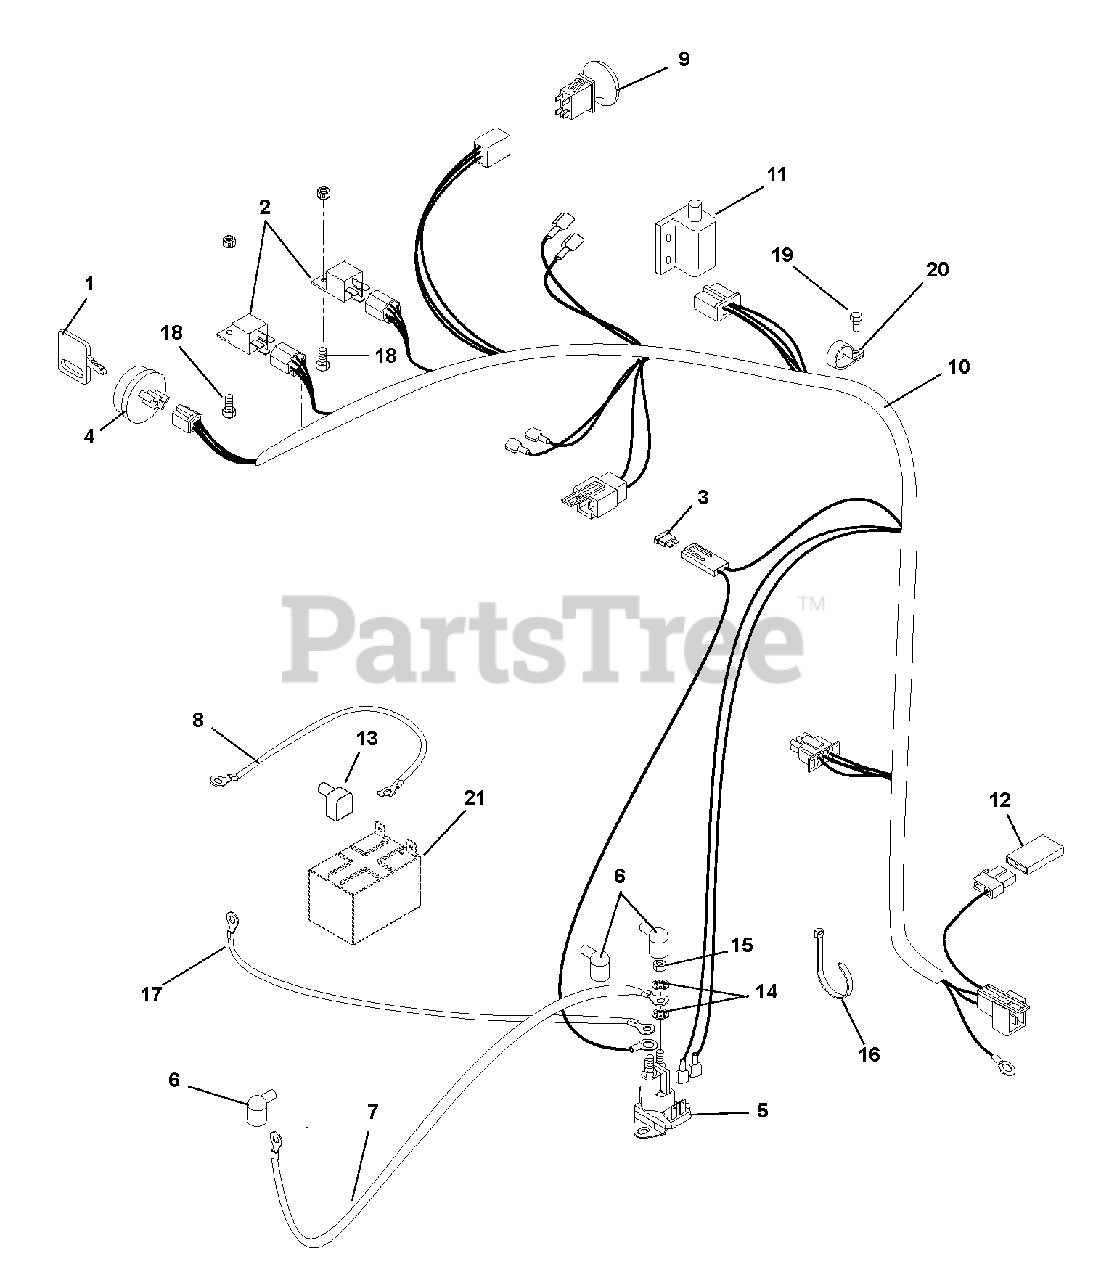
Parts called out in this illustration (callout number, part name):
1	Key with Cap
2	Relay
3	Fuse, 30 AMP
4	Key Switch
5	Solenoid
6	Boot, Eyelet Terminal
7	Starter Cable
8	Cable, Ground .25 x 13.00 x .31
9	Switch, Clutch With Retainer
11	Switch, Double Pole N.O. / N.O.
12	Diode, Connector Shell
13	Insulator
14	Washer, Locking .31
15	Nut, Jam .31-24
16	Cable Tie
17	Starter Cable
18	Screw, Hex Washer Head Machine 10-24 x .75
19	Screw, Tapping Hex Washer Head Thread Rolling .38-16 x .50
20	Clamp, Cushioned Steel .75
21	Battery, 215 CCA GEP
